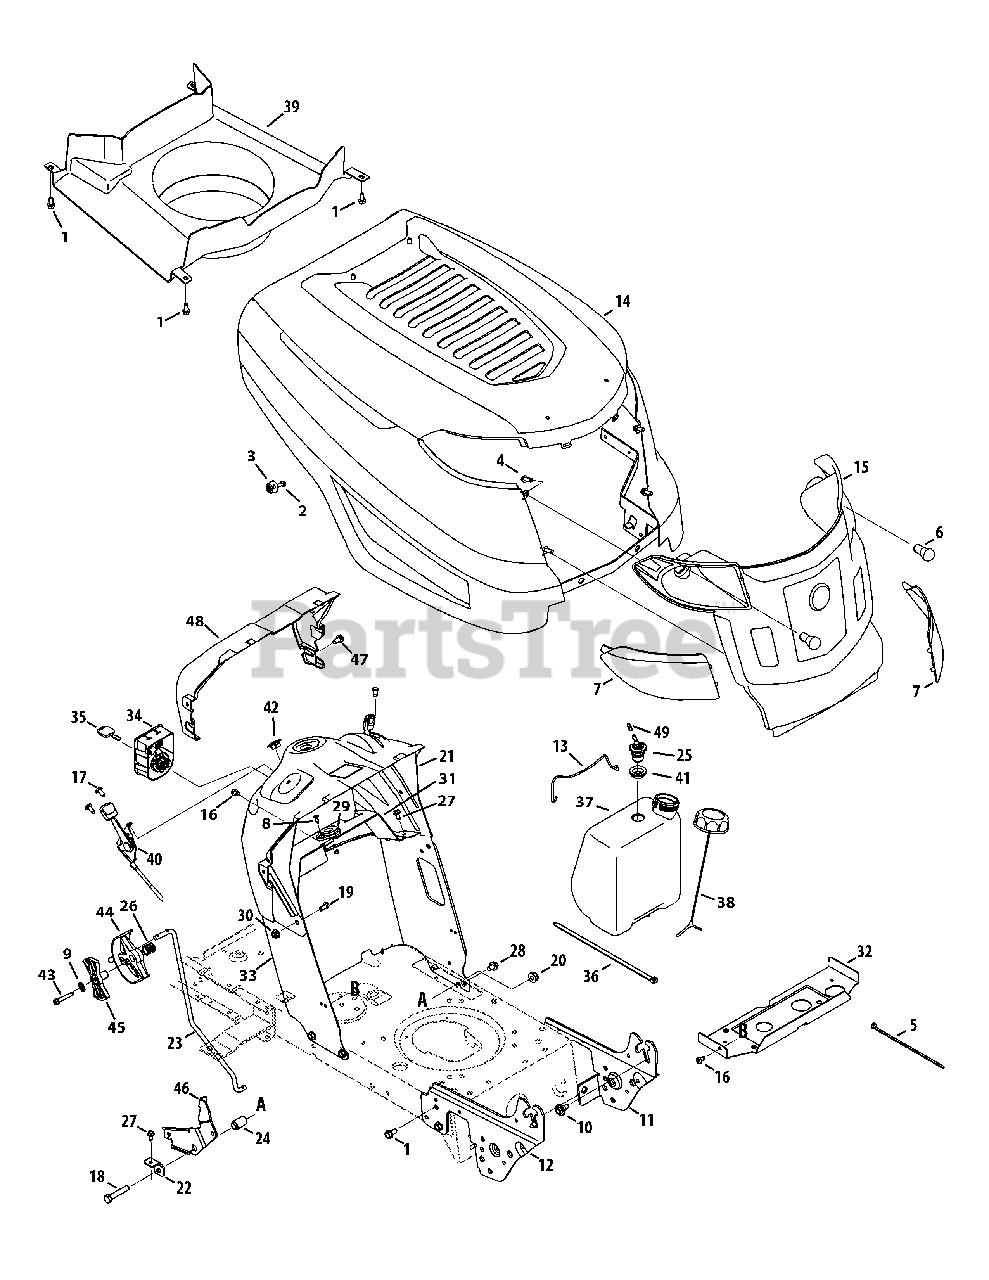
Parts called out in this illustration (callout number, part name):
1	Screw 5/16-18 x .750
2	Screw, #12-16 x 1.25
3	K-Style Bumper
4	Screw, 1/4 x .750
5	Cable Tie
6	Miniature lamp 12V socket
7	Grill Lens - LH
7	Grill Lens - RH
8	Screw, #10-16 x .500
9	Lock Washer, 1/4
10	Shoulder Screw .43 x .29
11	Suppport Bracket LH
12	Suppport Bracket RH
13	Battery Rod
15	Grille Assembly, K-Style
16	Screw, 1/4-20 x .500
17	Screw 1/4-20 x .500
18	Hex Screw 3/8-16 x 2.00
19	Hex Screw, 5/16-18 x .625
20	Flange Lock Nut 3/8-16
21	Dash, Upper,
22	Speed Latch Tab
23	Speed Control Rod
24	Flange Spacer .39 x .671 x 1.095
25	Rollover Valve
26	Compr. Spring, .72 OD x .78
27	Tap Screw, 1/4-20, 0.625
28	Screw 5/16-18 x .625
29	Bearing, .628 ID x 1.36
30	Flange lock Nut 5/16-18
31	Bracket, Steering Support
32	Gas Tank Support Bracket
33	Dash, Lower NWNDW
34	Key Switch Module
36	Cable Tie
37	1.36 Gallon Fuel Tank
38	Fuel Cap, 2.25"
39	Plenum
40	Throttle/Choke Cable, 28"
41	Rubber Grommet, 23 x 3.55
42	Choke Plug
43	Hex Washer Screw, 1/4-20 x 1.50
44	Shift Lever
45	Index Control
46	Transmission Speed Latch, RMC
47	Screw, 1/4-15 x .750
48	Dash Collar
49	Hose Vent, 3/16 EPA
